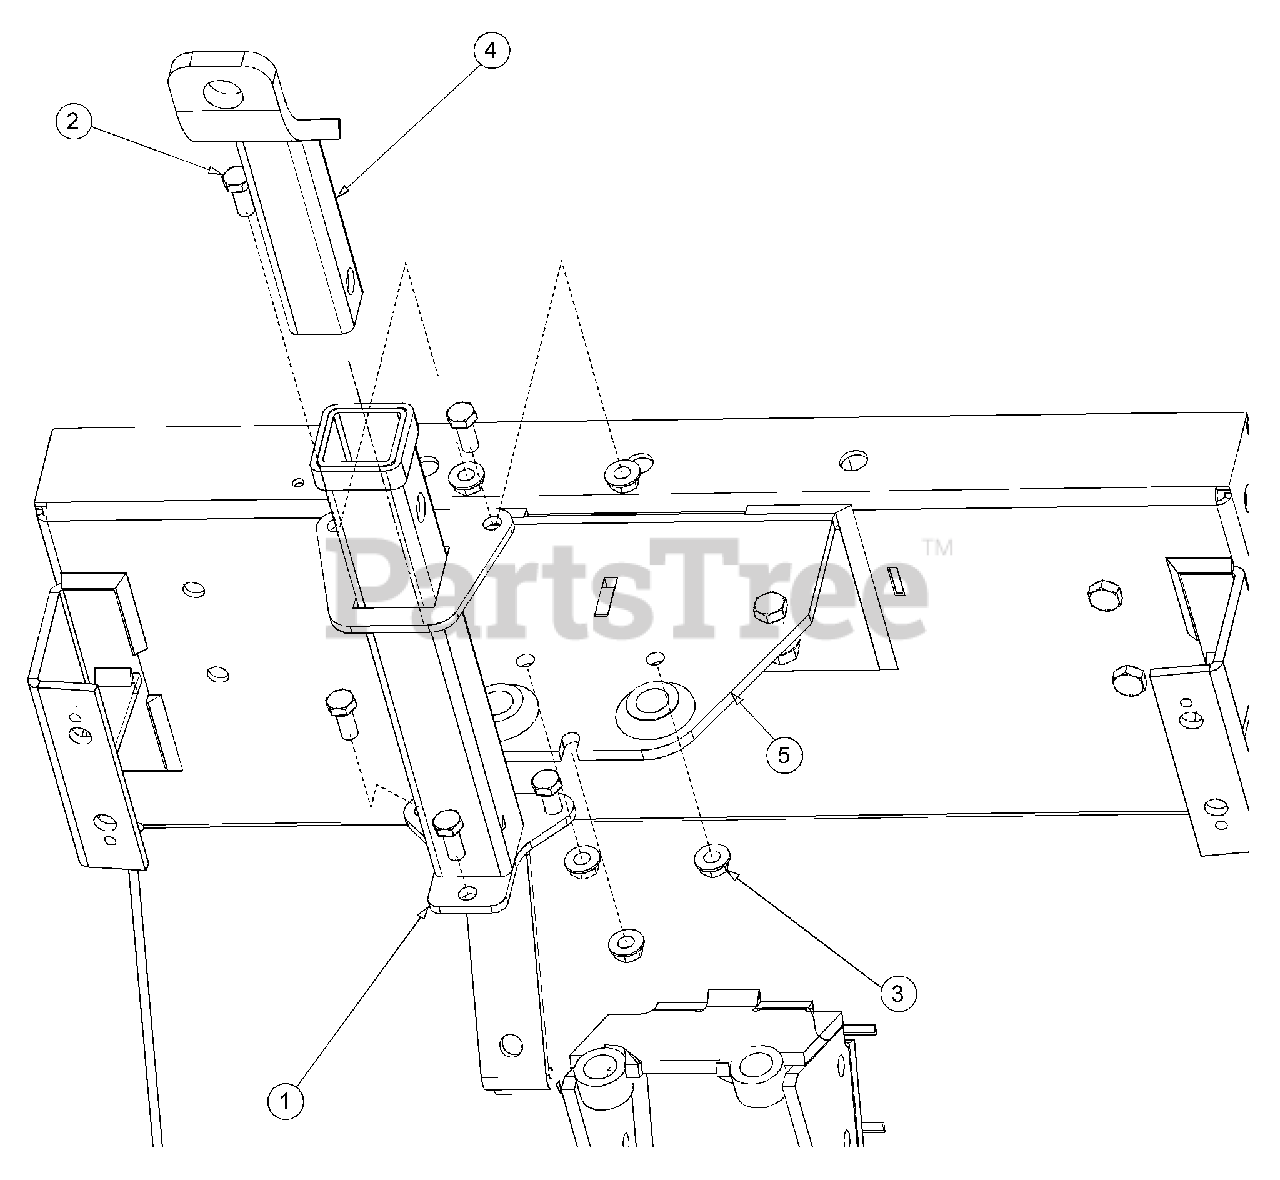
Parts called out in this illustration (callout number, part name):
1	Hitch, Assembly
2	Screw, 5/16-18 x .75 GR 5
3	Nut, Flangelock 5/16-18 GR 5
5	Mating Assembly
